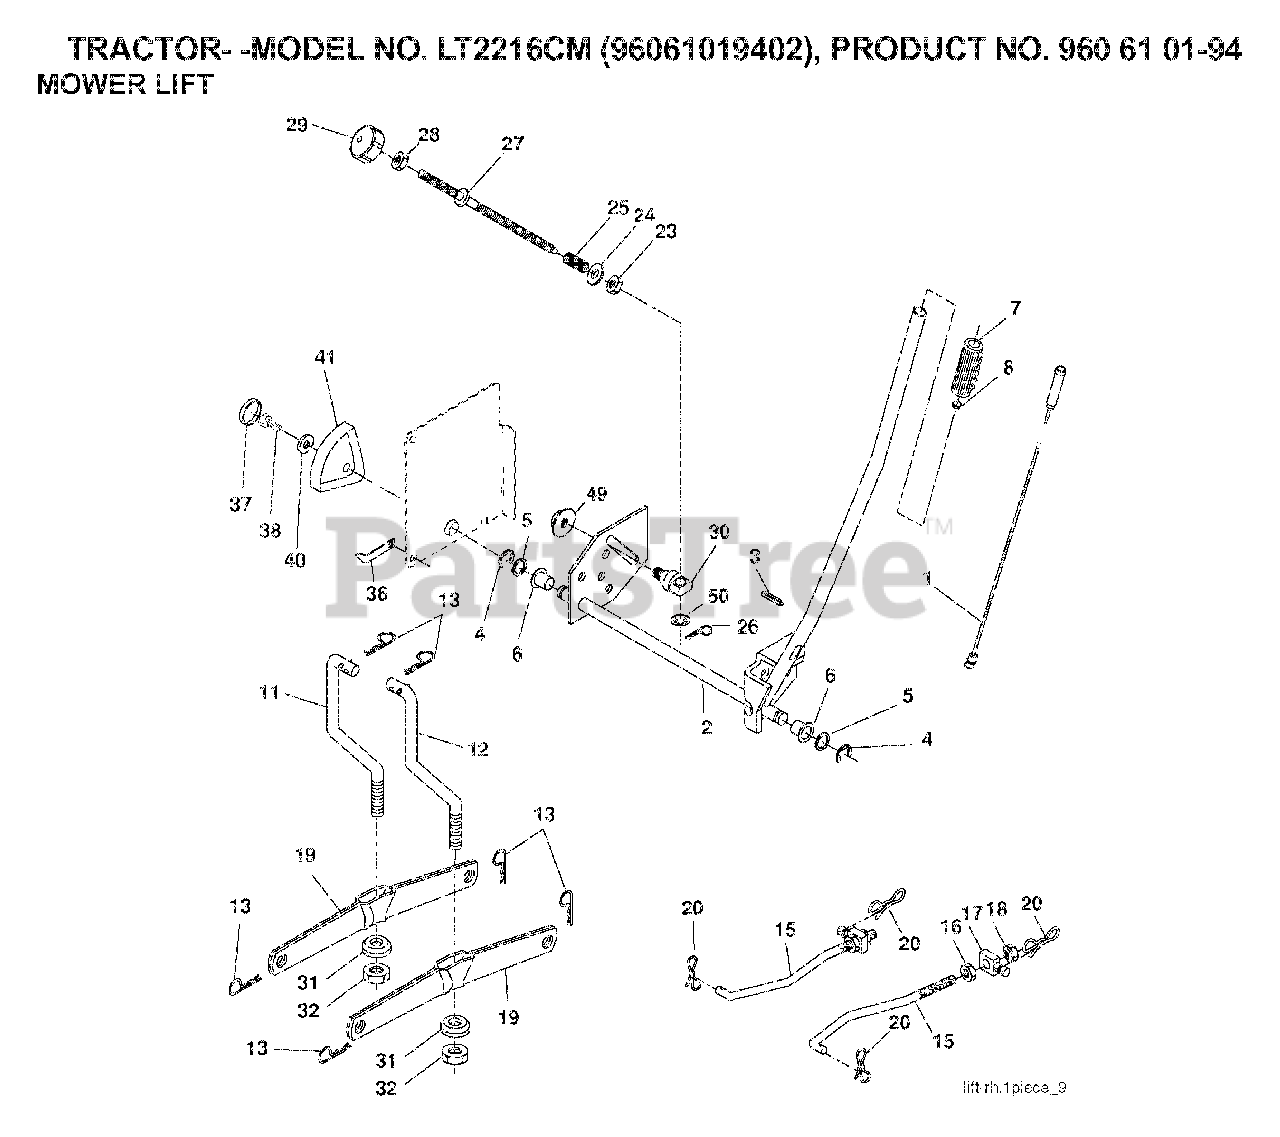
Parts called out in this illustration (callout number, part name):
4	RETAINING RING LT
6	BEARING.NYLON
7	GRIP HANDLE
8	PLUNGER BUT KIT
11	LINK
12	LINK
13	RETAINER-SPRNG RB
15	LINK.SUSPENSION.FRONT
16	NUT
18	NUT
19	ARM.REAR.SUSPENSION
20	PIN.COTTER.7/16.BOW TI
25	SPRING**
26	RETAINER CLIP
27	ROD ADJ LIFT
28	NUT
29	KNOB INF 3/8-16
31	BEARING.PIVOT.LIFT
32	NUT CROWNLOCK 3/8-24
36	POINTER, HEIGHT INDICATOR
37	PLUG,HOLE
38	SCREW 5/16-18X1
41	HEIGHT INDICATOR
49	NUT
50	NUT PUSH M
